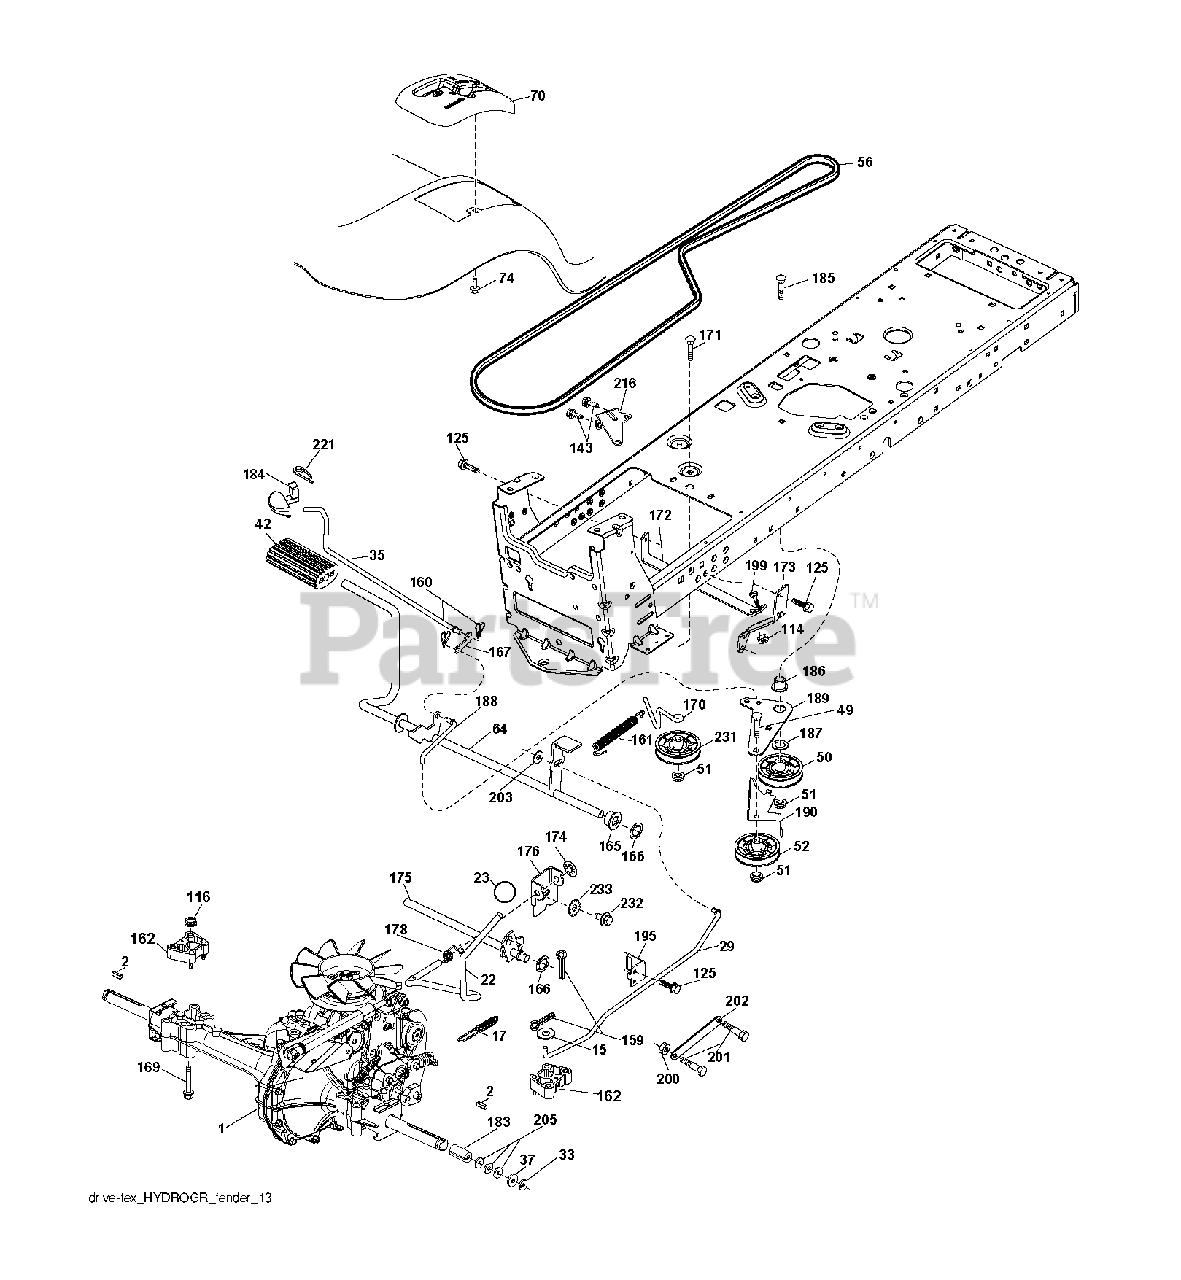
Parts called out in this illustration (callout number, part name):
2	SQUARE KEY
17	SPRING.BRAKE.HG3000/3500
22	ROD.SHIFT.FENDER.TLT.2006
23	KNOB.DUCKHEAD.1/2
29	ROD.BRAKE.HG-0510
33	E-RING LT
35	ROD.BRAKE.PARKING.LT.T
42	PEDAL COVER T
49	BOLT
50	IDLER.FLAT.910.OFFSET
51	NUT LOCK FLG 3/8-16 UNC
52	IDLER.V-GROOVE.910.OFFSET
64	SHAFT.ASM.PEDAL.BRAKE.
70	CONSOLE.SHIFT.STL.HYD.BLACK
74	SCREW.HI-LO.CONSOLE
114	NUT.71038.31-18.HEX.NYLOCK
116	NUT LOCK HEX FLANGE 5/16-18
125	SCREW
148	SCREW, 3/8-16X3/4
159	COTTER PIN
160	RETAINER CLIP
161	SPRING.RETURN.CLUTCH.2006
162	SPACER.TRANSAXLE.18&22
165	BUSHING.SHAFT.BRAKE.HAND
166	NUT.PUSH.625.2006
167	LATCH.BRAKE.SPRING
169	BOLT.HEX.FLNG.5/16-18X3.75
170	KEEPER.V-IDLER.CENTER.
172	STRAP.TRQ.LH.FS.HG0510
173	STRAP TORQUE RH
174	NUT.PUSH.500.2006
175	SHAFT.ASM.SHFT.HG0510/
176	ARM.CLEVIS.ROD.SHIFT
178	SPRING.SHIFT.GT2006
183	SPACER AXLE
184	HANDLE.PAKRING.BRAKE.
186	SPACER.RETAINER
187	WASHER 12/32X2X10GA
188	LINK.CLUTCH.GROUND.DRIVE
189	BELLCRANK.GROUND.DRIVE.TEX.
190	KEEPER.BELLCRANK.DRIVE
195	BRKT.ROD.BRAKE.18/20/2
199	BOLT
200	NUT.CENTERLOCK.5/16-
201	BOLT SHOULDER 5/16-18 UNC
202	LINK TRANS
203	WASHER
216	BRACKET.PULLEY.IDLER.W/TEX
221	RETAINER.SPRING.CLIP.H
231	IDLER.V-GROOVE.1.688.OFFSET
232	BOLT FIN HEX 7/16-14 X 1
233	WASHER SERRATED
268	WASHER
